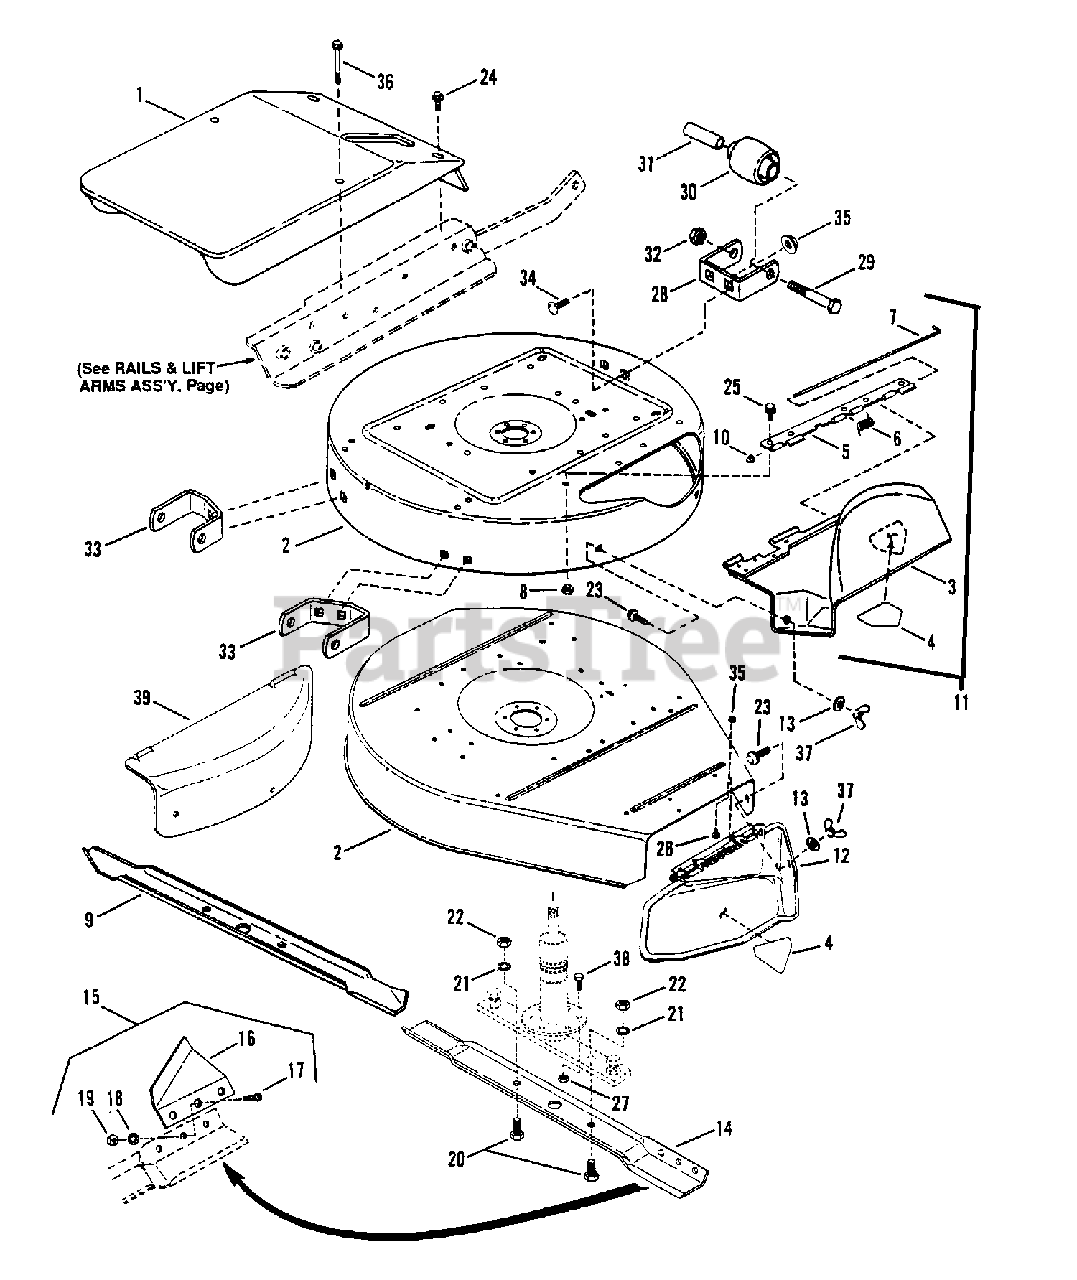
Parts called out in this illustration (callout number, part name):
1	COVER, Spindle
2	25" DECK (Includes decals)
2	28" DECK (Includes decals)
2	30" DECK (Includes decals & deflector)
2	33" DECK (Includes decals)
3	DEFLECTOR, Discharge (25" Deck)
3	DEFLECTOR, Discharge (28" & 33" Deck)
4	DECAL, Danger (Cut Finger)
5	HINGE, Deflector
6	SPRING, Hinge
7	PIN, Hinge
8	NUT, 5/16-18 Hex Flange Lock
9	BLADE, 25" Mulcher
9	BLADE, 28" Mulcher
9	BLADE, 33" Mulcher
10	NUT, Push
11	ASSEMBLY, Discharge (25" Deck)
11	ASSEMBLY, Discharge (28" & 33" Deck)
12	ASSEMBLY, Discharge (30" Decks)
13	WASHER, 5/16 Flat
14	25" BLADE
14	28" BLADE
14	30" BLADE
14	33" BLADE
15	AIR LIFT KIT, Hi-Vac
16	AIR LIFT, Hi-Vac (3 hole)
17	SCREW, 5/16-24 x 11/16" Machine
18	WASHER, 5/16-24 Internal Tooth Lock
19	NUT, 5/16-24 Hex
20	SCREW, 1/2-20 x 1" Hex Head Cap
21	WASHER, 1/2 Internal Tooth Lock
22	NUT, 1/2-20 Hex Jam
23	BOLT, 5/16-18 x 3/4" Short Neck Carriage
24	SCREW, 1/4-20 x 5/8" Self-Tapping
25	SCREW, 5/16-18 x 1/2" Self-Tapping
26	BOLT, 5/16-18 x 1/2" Hex Flange Lock
27	NUT, 3/18-16 Hex Flange Lock
28	BRACKET, Gage Wheel (Front)
29	SCREW, 38-24 x 3-3/4" Hex Head Cap
30	WHEEL, Gage
31	SPACER
32	NUT, 3/8-24 Hex Lock
33	BRACKET, Gage Wheel (Rear)
34	BOLT, 5/16-18 x 1/2" Short Neck Carriage
35	NUT, 5/16-18 Hex Flange Lock
36	SCREW, 1/4-20 x 3-1/2" Self-Tapping
37	NUT, 5/16-18 Wing
38	BOLT, 3/8-16 3/4" Hex Flange Lock
39	COVER, 25" Mulcher
39	COVER, 28" Mulcher
39	COVER, 33" Mulcher
